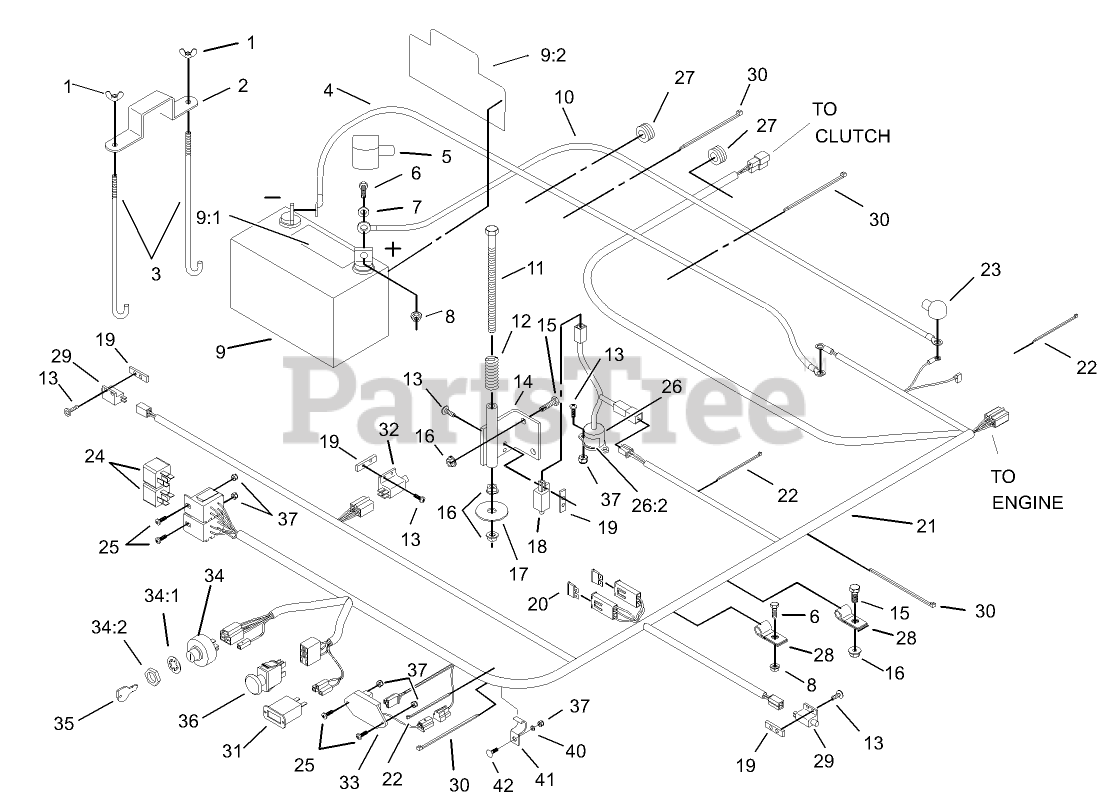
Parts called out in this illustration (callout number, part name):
1	WINGNUT
2	STRAP-HOLDDOWN
3	BOLT-HOLDDOWN
4	CABLE-GROUND, NEGATIVE
5	INSULATOR-BATTERY
6	SCREW-HH
7	WASHER-FLAT
8	NUT-HF
9	BATTERY
9:1	Decal-Battery
9:2	Decal-Battery
10	WIRE-STARTER
11	SCREW-HH
12	SPRING-SWITCH, SEAT
13	SCREW-PPH
14	BRACKET-SWITCH, SEAT
15	SCREW-HH
16	NUT-HF
17	WASHER
18	SWITCH-CLOSED, NORMALLY
19	PLATE-TAPPED
20	FUSE-BLADE TYPE, 20 AMP
21	HARNESS-WIRE
22	TIE-CABLE
23	INSULATOR-SOLENOID
25	BOLT-CARR
26	TILT SWITCH ASM
26:2	DECAL-SWITCH, MERCURY
27	GROMMET
28	CLIP-LOOM
29	SWITCH-OPEN, NORMALLY
30	TIE-PLASTIC
31	METER-HOUR
32	SWITCH
33	MODULE-DELAY, SEAT
34	Key Switch ASM
34:1	WASHER-TOOTH, INTERNAL
34:2	NUT-HH
35	KEY-IGNITION
36	SWITCH-DELTA
37	NUT-LOCK, NI
40	WASHER-FLAT
41	CLIP-HALF, LOOM
42	BOLT-CARR
